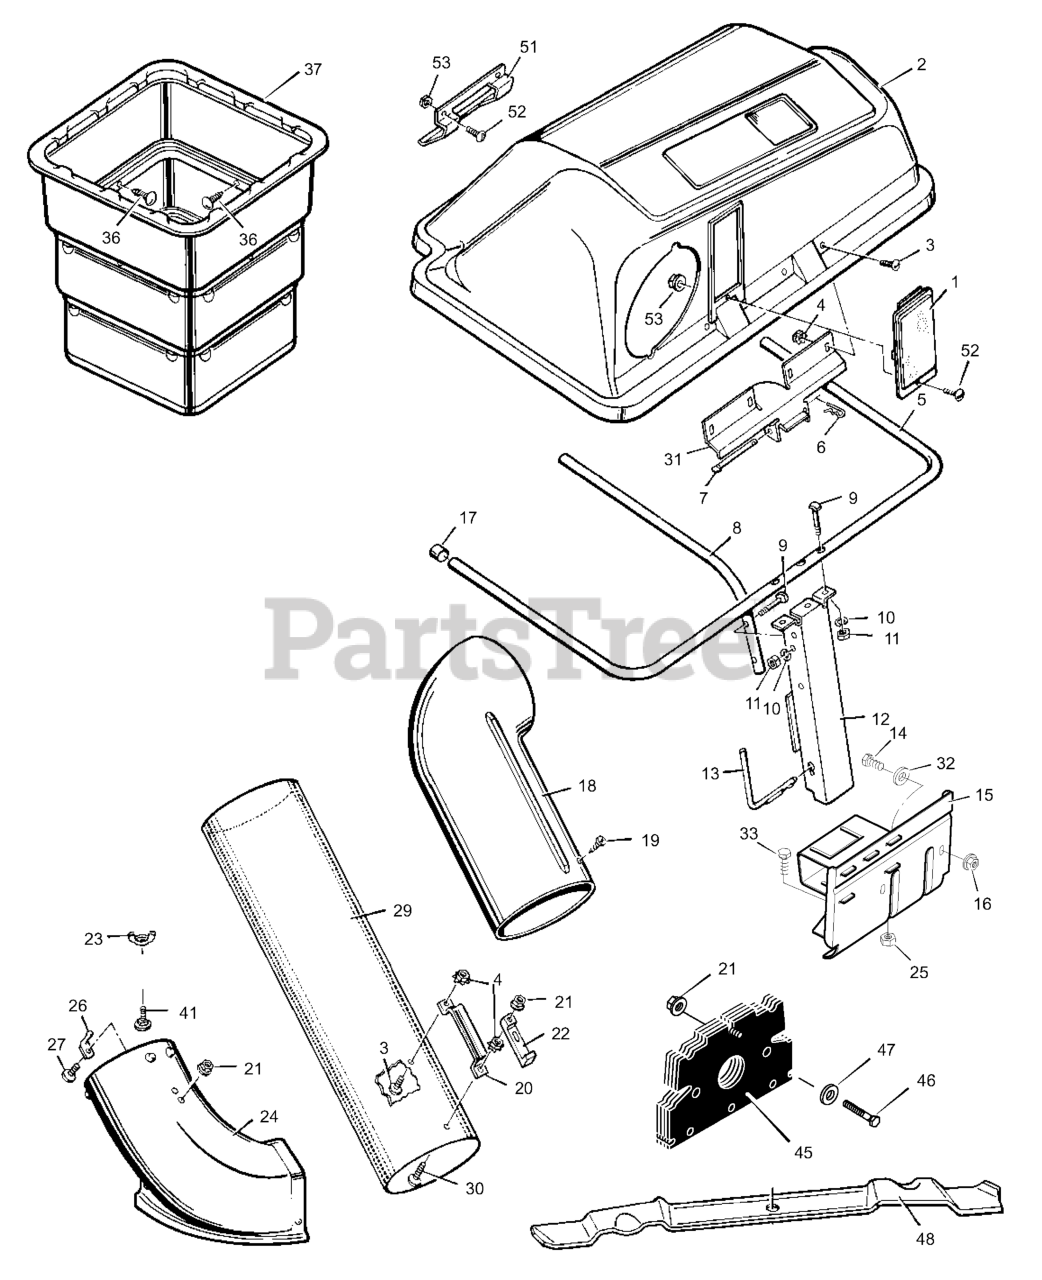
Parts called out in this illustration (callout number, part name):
4	Locknut
6	Pin, Hair
7	Pin, Hinge
8	Tube, Center
9	Bolt, Special
10	Lockwasher
11	Nut, Hex
12	Channel Assembly
13	Pin, Channel
14	CAPSCREW, Hex Head, 5/16-18 x 1
15	Mount Assembly, Bagger
16	Nut, Hex
17	Cap, End
20	HANDLE, Connect Tube
21	Locknut, Flange
22	Latch, Rubber
23	Wingnut
24	Tube, Extension
25	Hex Nut
26	Pin, Latch
27	Bolt, Carriage
29	Tube, Connector
31	Hinge, Cover
33	Bolt, Hex
36	Fastener, Plastic
37	Containers (Quantity 2)
41	Bolt, Carriage
42	Handle, Plastic
44	Nut, Hex
45	Weight, Front
46	Bolt, Hex
48	Blade, 97cm (38-inch)
